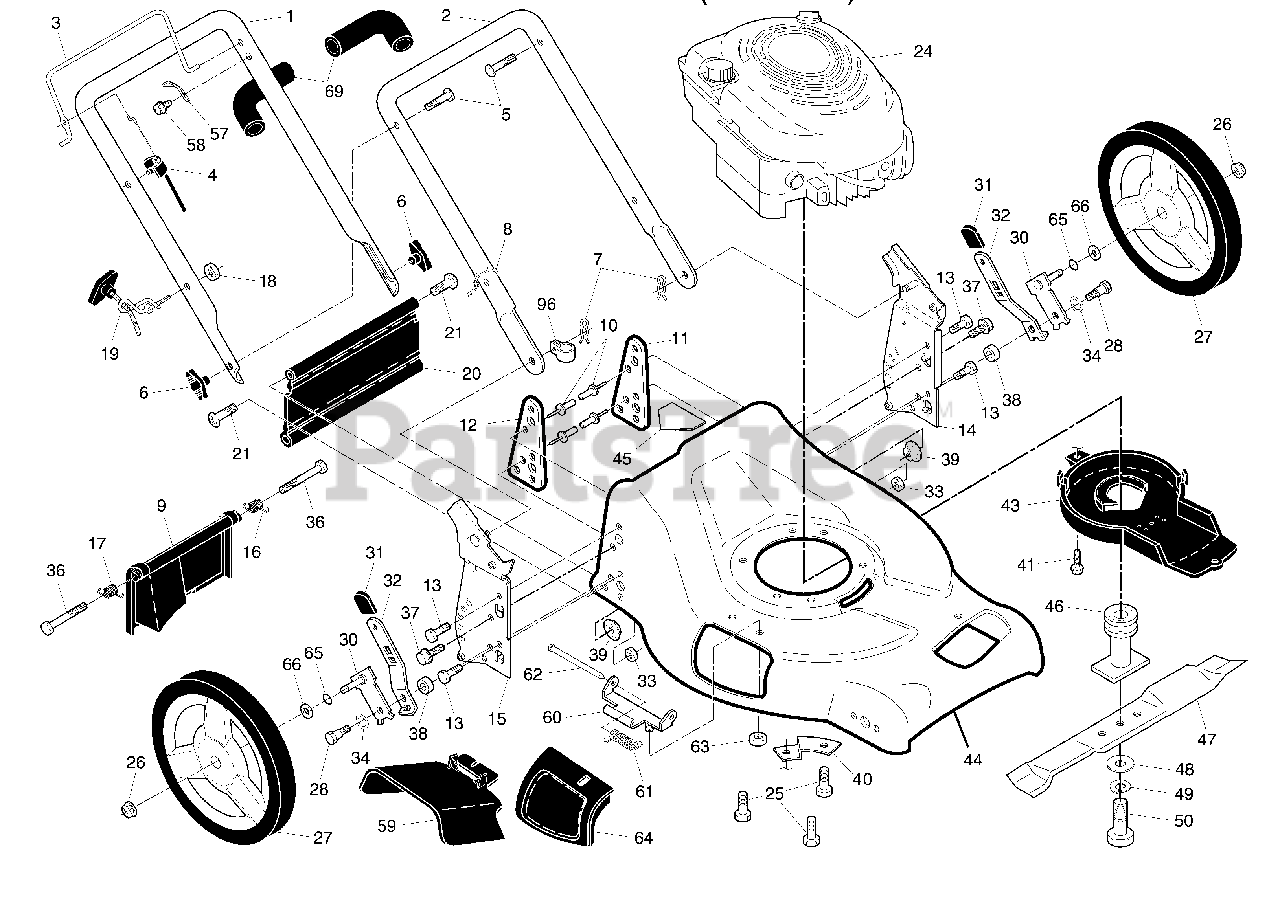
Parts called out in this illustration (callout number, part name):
1	Upper Handle, with Foam Grip
2	Lower Handle
3	Control Bar
4	Engine Zone Control Cable
5	Handle Bolt
6	Handle Knob
7	Hairpin Cotter
8	Wire Tie
9	Rear Door Assembly
11	Support Bracket, LH
12	Support Bracket, RH
13	Screw 1/4-20 x 5/8
14	Handle Bracket Assembly, LH
15	Handle Bracket Assembly, RH
16	Spring, Rear Door, LH
17	Spring, Rear Door, RH
18	Keps Locknut 1/4-20
19	Rope Guide
20	Rear Skirt
21	Screw, Hinge 1/4-20 x 1/2
25	Hex Head Thread Rolling Screw 3/8-16 x 1-1/8
26	Hex Flange Nut
27	Wheel & Tire Assembly, Rear, 12"
28	Shoulder Bolt 5/16-18 x .33
30	Axle Arm Assembly, Rear
31	Selector Knob
32	Selector Spring
33	Nut, Hex 5/16-18
34	Washer, Curved, Cylindrical
37	Thread Cutting Screw w/Sems 5/16-18 x 3/4
39	Nut, Hex
40	Mounting Bracket, Debris Shield
43	Debris Shield
44	Kit, Lawn Mower Housing
45	Danger Decal
46	Blade Adapter / Pulley
47	Blade, 21"
48	Hardened Washer
49	Helical Washer 3/8-24 x 1-3/8 Grade 8
50	Hex Head Machine Screw 3/8-24 x 1-3/8 Grade 8
57	Upstop Bracket
59	Discharge Deflector
60	Hinge Bracket
63	Nut, Hex
64	Mulcher Door
66	Washer, Flat 1/2
69	Grip, Foam
96	Clip, Cable
